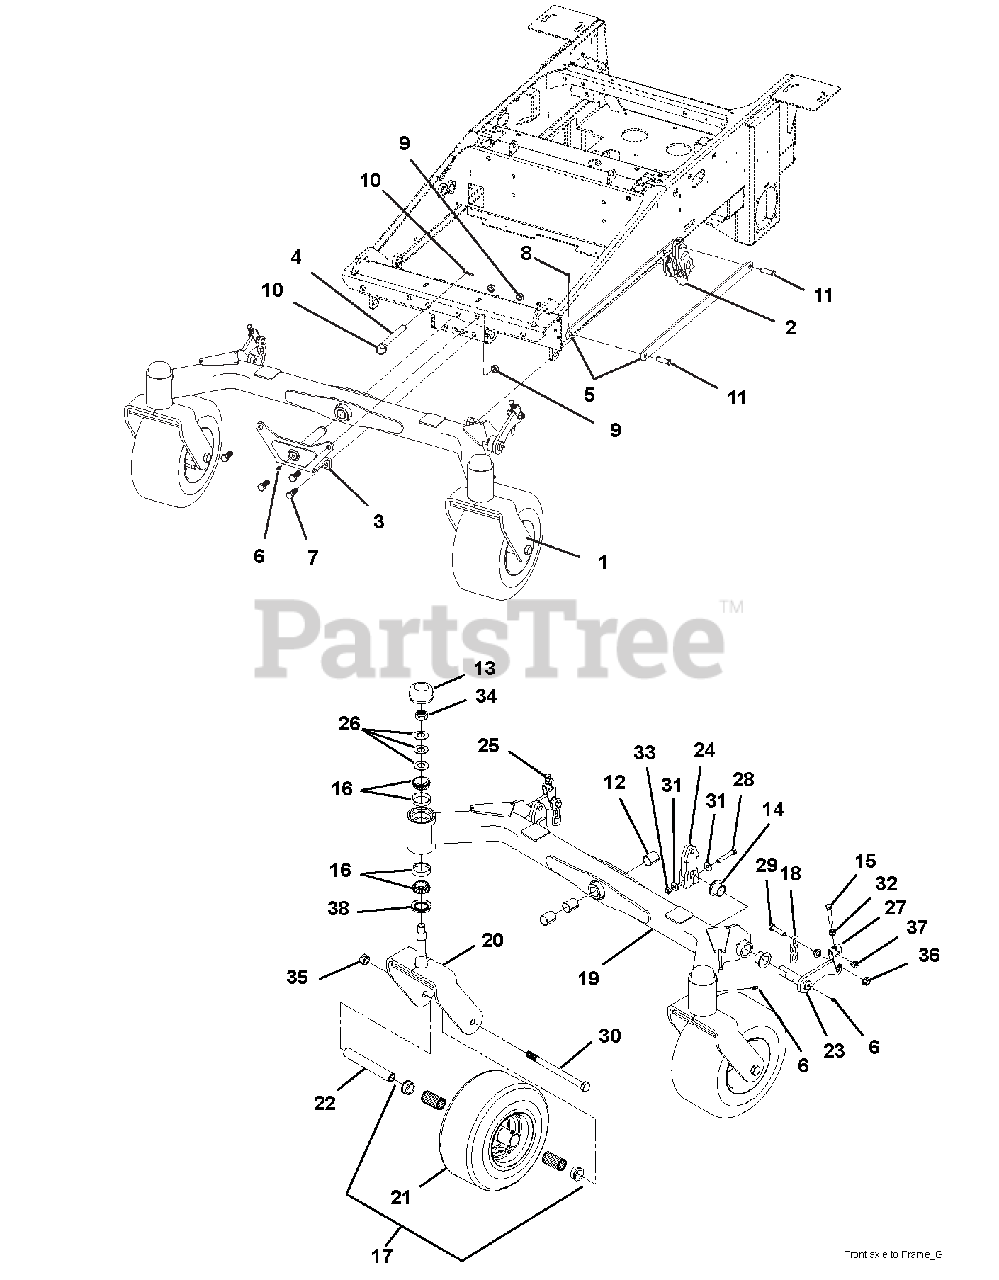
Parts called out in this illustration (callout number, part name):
1	Front Axle Frame Assembly (see view at bottom of p. 16 for individual componen
2	ASSY, REAR LIFT ROD
3	WLDT, FRONT AXLE BRACKET
4	PIN, MFG .625X5.00X4.38 XDRL Y
5	PLATE, CONNECTOR LINK
6	FTG, 1/4-28 STRGT GREASE ZERK
7	BOLT, 1/2-13X1.25 HEX 5 Y
8	RING, RUE .500 X .062 X 1.420
9	NUT-LK-CONE .50-13 GR C YWZC
10	RING, WIRE - .080 X 1.25
11	PIN-CLEV .50X1.50X1.27 YWZC
12	BEARING, SLV 1.00X1.13X1.25
13	CAP, SPINDLE
14	BRG, FLG 1.00X1.25X.944
15	BOLT, 3/8-16X2.25 HEX 5 FLTD Y
16	BRG ASSY, 1IN DIA SPINDLE
17	KIT, BEARINGS & CAPS 1.00"
18	CHAIN, IMPLEMENT HOLD (3-LINK)
19	WLDT, FRONT AXLE
20	WLDT, Z FRONT WHEEL FORK
21	ASSY, TIRE & RIM - 13/6.50X6
21	TIRE/WHEEL ASSY 13X5-6(RIBBED)
22	TUBE, FRONT TIRE AXLE
23	WLDT, LH FRONT PIVOT
23	WLDT, RH FRONT PIVOT
24	WLDT, FRONT PIVOT CLAMP
25	ASSY, DECK LEVELER
26	WASHER, .750X1.50X.072 BLVL U
27	LINK, U-BRACKET
28	@BLT-HEX .38-16X2.25 GR5 YWZC
29	BOLT, 7/16-14 X 2.00 HEX5SPC Y
30	BLT-HEX .62-11X8.5 GR5 YWZC
31	@WSHR-FL-STL.438X1.00X.083 YWZ
32	@NUT-SPNLK-FLG .375-16 YWZC
33	NUT-LK-FLG .375-16 PL
34	LOCKNUT, 3/4-16 CROWN GR 8 Y
35	@NUT-LK-CTR .50-13 YWZC
36	NUT-FLANGED WHIZ .438-14 YWZC
37	NUT, 3/8-16 SQUARE Y
38	SEAL, BRG 1.00 ROLLER
